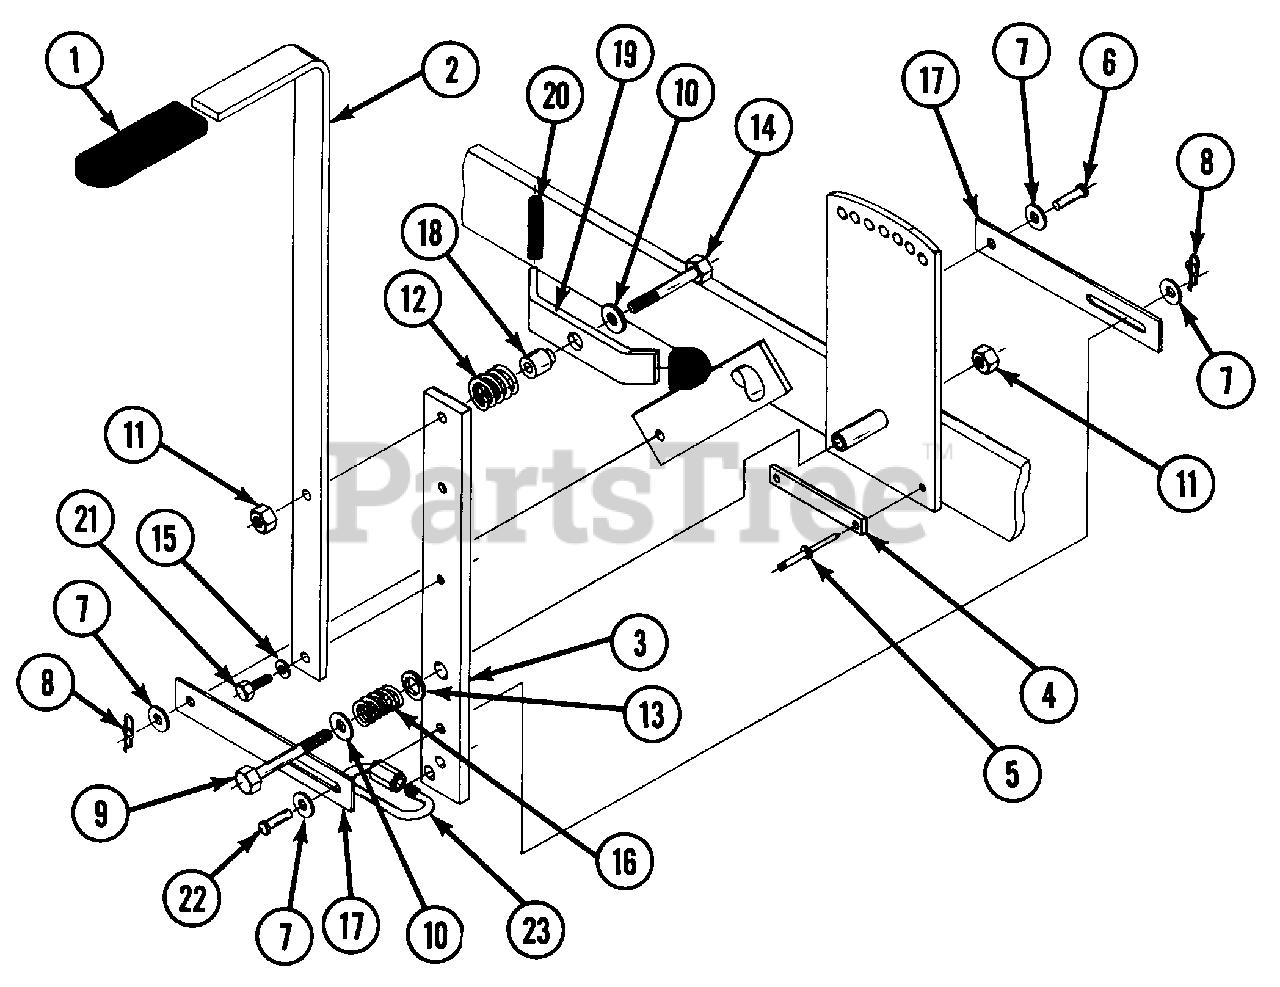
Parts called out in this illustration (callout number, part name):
1	GRIP, VINYL, 1/4 X 1
2	HANDLE, DECK LIFT, TOP
3	DECK HANDLE WELDMENT
4	SLIDE, DECK HANDLE
5	BLIND (POP) RIVET
6	PIN, CLEVIS, 5/16 X 7/8
7	WASHER, 5/16 STD, FLAT
8	COTTER, RUE RING, 5/16-3/8 PIN
9	CAPSCREW, HEX, 3/8-16 X 2-3/4, GRADE 5
10	WASHER, 3/8 STD FLATS W SERIES
11	LOCKNUT, HEX, 3/8-16 W/NYLOC
12	SPRINGER COMPRESSION
13	WASHER, .656 ID X 1 OD X 8 GA
14	CAPSCREW, HEX 3/8-16 X 2-3/8, GRADE 5
15	LOCKWASHER, 5/16 HEAVY, SPLIT SPRING
16	SPRING, COMPRESSION
17	LINK, HANDLE
18	LOCK STAND
19	LOCK ARM
20	GRIP, LOCK
21	CAPSCREW, HEX, 5/16-18 X 3/4, GRADE 5
22	PIN, CLEVIS, 5/16 X 27/32
23	CHAIN CONNECTOR
